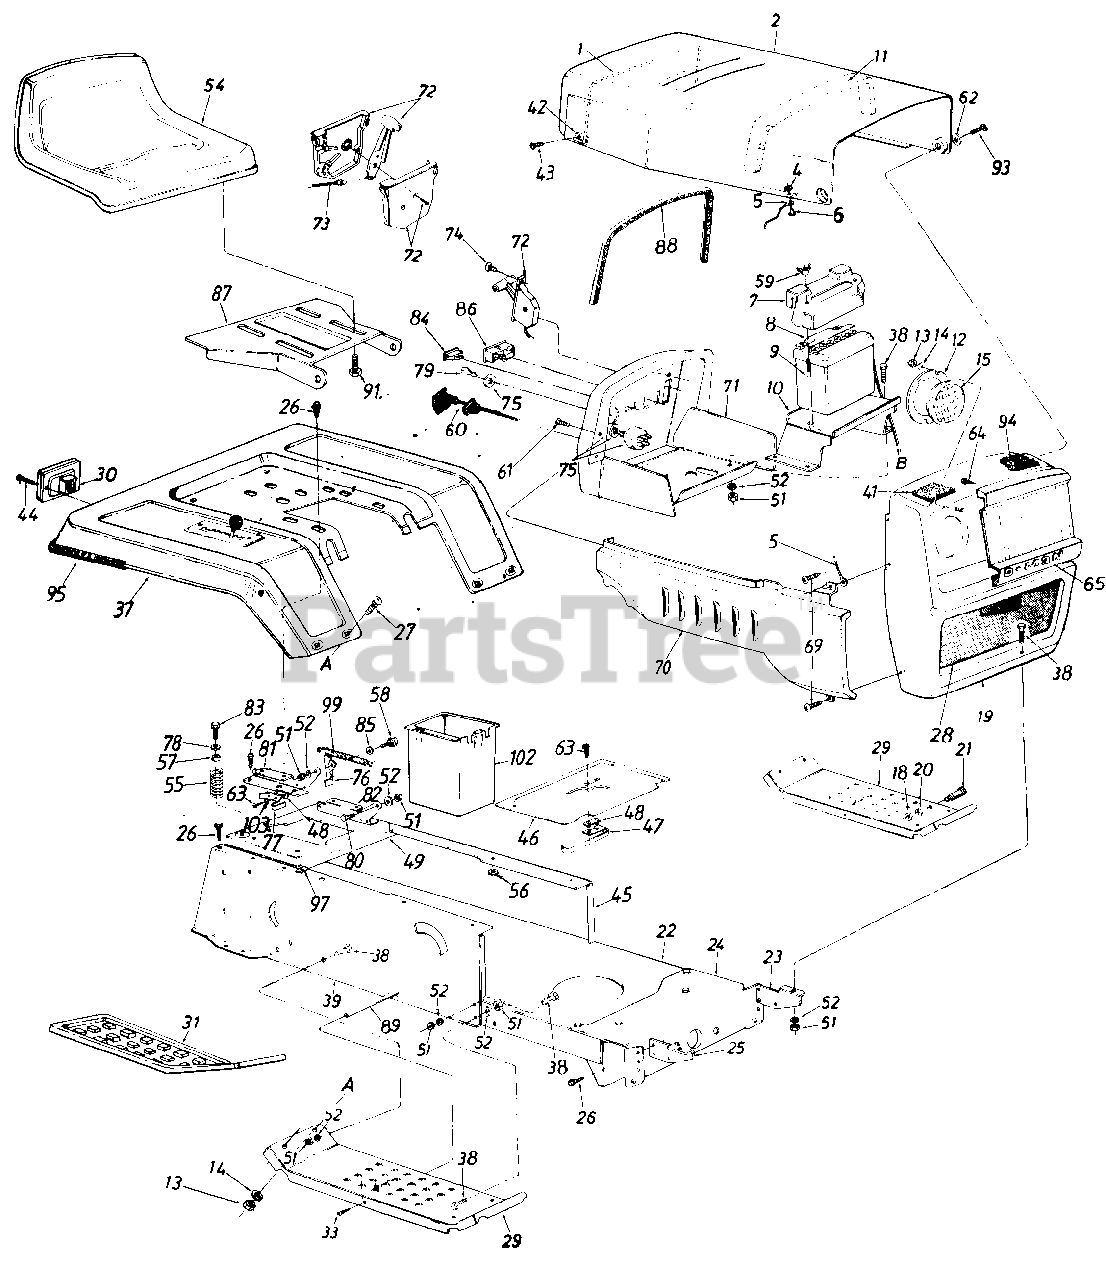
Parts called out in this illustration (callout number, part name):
1	Hood Spring
5	Hood Stop 7" Lg.
6	POP Rivet .188" Dia.
7	Battery Cover
8	12 Volt Battery
9	Battery Hold Down Rod
10	Battery Bracket
11	PVC Foam Strip
12	Headlight Retainer
13	Hex Nut 1/4-20 Thd.
14	L-Wash. 1/4" I.D.
15	Headlight
18	Hex Nut 3/8-16 Thd.
21	Shld. Bolt .50" Dia. x .84
22	Lower Frame
23	Grille Mount Brkt.
24	Front Pivot Brkt.
25	Grille Mount Brkt.
26	Hex Wash. Hd. AB-Tap Scr. 5/16 X .75" Lg.
27	Carriage Bolt 1/4-20 x .50" Lg.
28	Grille Insert
29	Running Board
30	Taillight
31	Foot Pad L.H.
33	Truss Mach. Scr. 5/16-18 x .75" Lg.
37	Fender
38	Hex Bolt 5/16-18 x .75" Lg.
39	R.H. Side Frame
41	Foam Strip
42	Hood Spring Retainer
43	Self-Tap Scr. .5" Lg.
44	Truss AB-Tap Scr. #6 X .62" Lg.
45	L.H. Side Frame
46	Shift Cover
47	Reverse Safety Switch
48	Insulator Nut Plate
49	Hitch Plate
51	Hex Nut 5/16-18 Thd.
52	L-Wash. 5/16" I.D.
54	Seat Ass'y.
55	Compression Spring
56	Ext. L-Wash. 5/16" I.D.
57	Bushing
58	Shld. Bolt .437" Dia. x .268"
59	Wing Nut 1/4-20 Thd. Plastic
60	Choke Control 46" Lg.
61	Truss Mach. Tap Scr. #10 x .50" Lg.
62	Washer 39" I.D. x .62" O.D.
63	Hex Wash. Hd. AB-Tap Scr. #8 x .50
64	Self-Tap Scr. #8 x .5" Lg.
65	Bezel
69	Truss Hd. Scr. 1/4-20 x 75" Lg.
70	R.H. Grille Side Panel
71	Dash Panel Ass'y.
72	Throttle Control Box Ass'y.
73	Throttle Control Wire 35"
74	Truss Mach. AB-Tap Scr. #10 x .5" Lg.
75	Ignition Switch
76	Seat Lift Bracket
77	Spring Switch
78	Fl-Wash. .344" I.D.
79	Ignition Key
80	Shld. Bolt .437" Dia. x .162"
81	Seat Pivot Brkt. Support R.H.
82	Seat Pivot Brkt. Support L.H.
83	Hex Hd. Tap Scr. 5/16-18 x 1" Lg.
84	Light Switch
85	Spr-Wash. .445" I.D. x .75" O.D.
86	Ammeter
87	Seat Pivot Bracket
88	Molding Strip 27" Lg.
89	Running Board Rod
91	Hex Wash. Hd. Tap Scr. 3/8-16 x .75" Lg.
93	Shld. Bolt .375 Dia. x .125
94	L-Nut 1/4-28 Thd.
95	Trim Strip 31.0" Lg.
97	Speed Nut #10Z
99	Extension Spring 5.31" Lg.
102	Utility Box
103	Fiber Washer
